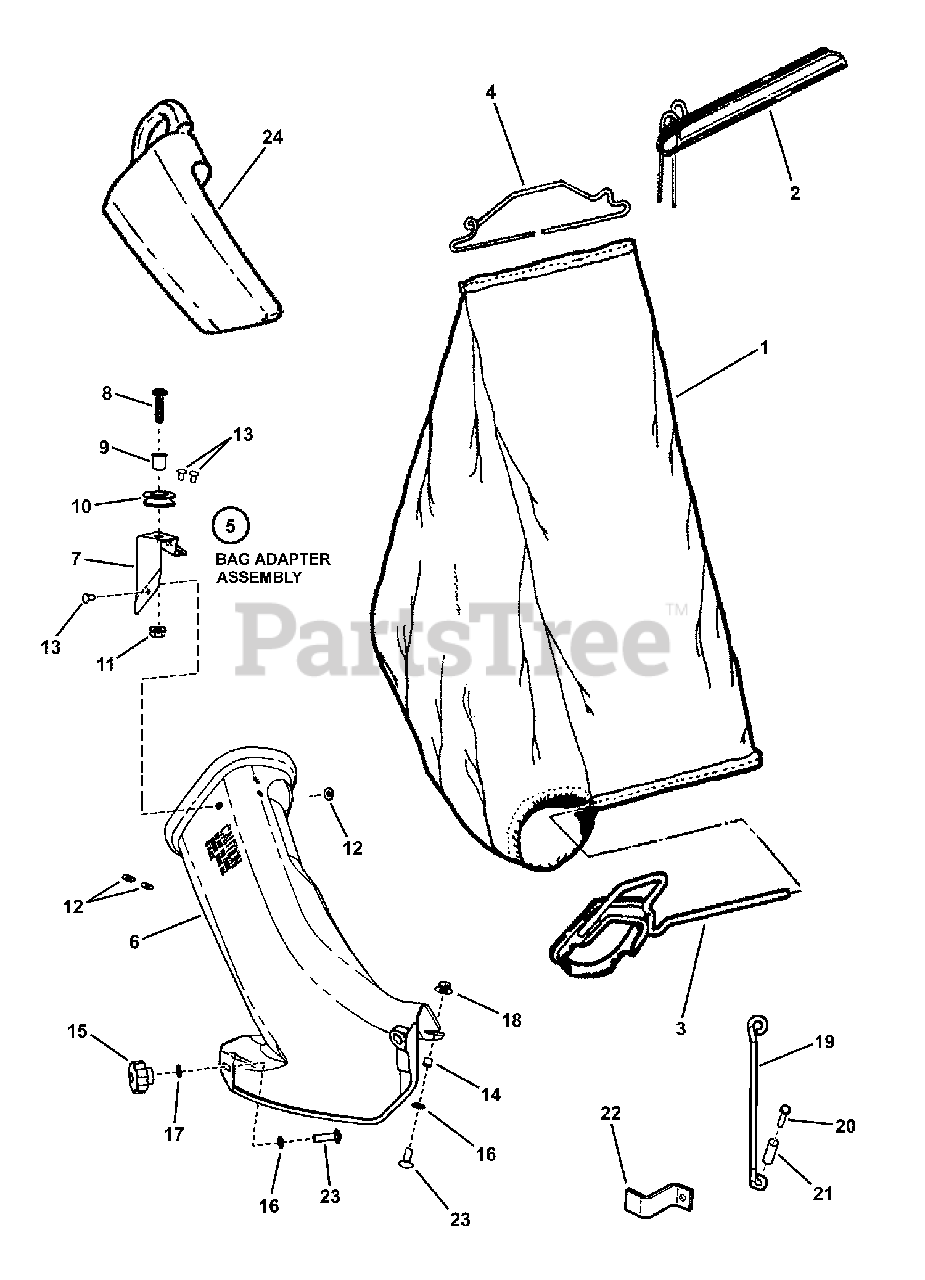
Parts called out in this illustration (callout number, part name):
1	GRASS BAG, Slider Type (Black w/Gray Letters)
2	ASSEMBLY, Slider
3	CONNECTOR, Grass Bag
4	WIRE, Bag Connector (12" Wide)
5	ASSY, Grass Bag Adapter (Incl. items 6 thru 13)
6	ADAPTER, Grass Bag
7	BRACKET, Rope Pulley
8	SCREW, 5/16-18 x 1-1/4" Pan Head Machine
9	BUSHING, Flange (Powdered Metal)
10	PULLEY, Plastic
11	NUT, 5/16-18 Hex Flange Lock GR 5
12	WASHER, 15/32" Flat
13	RIVET, 3/16 x .344
14	SPACER, .316 I.D. x .375 O.D. x .310 thick
15	KNOB, Fluted, 5/16-18 x .633
16	RETAINER, 5/16" Bolt
17	WASHER, 5/16" Flat
18	NUT, 5/16-18 Hex Large Flange Center Lock
19	BRACE, Bag Adapter, KWV
20	SCREW, M6 x 1.0 x 30mm Hex Head Cap
21	SLEEVE, .237/.242 I.D. x .3135/.3185 O.D. x .748
22	STANDOFF
23	BOLT, 5/16-18 x 3/4" Short Neck Carriage GR 5
24	PLUG, Chute Adapter
